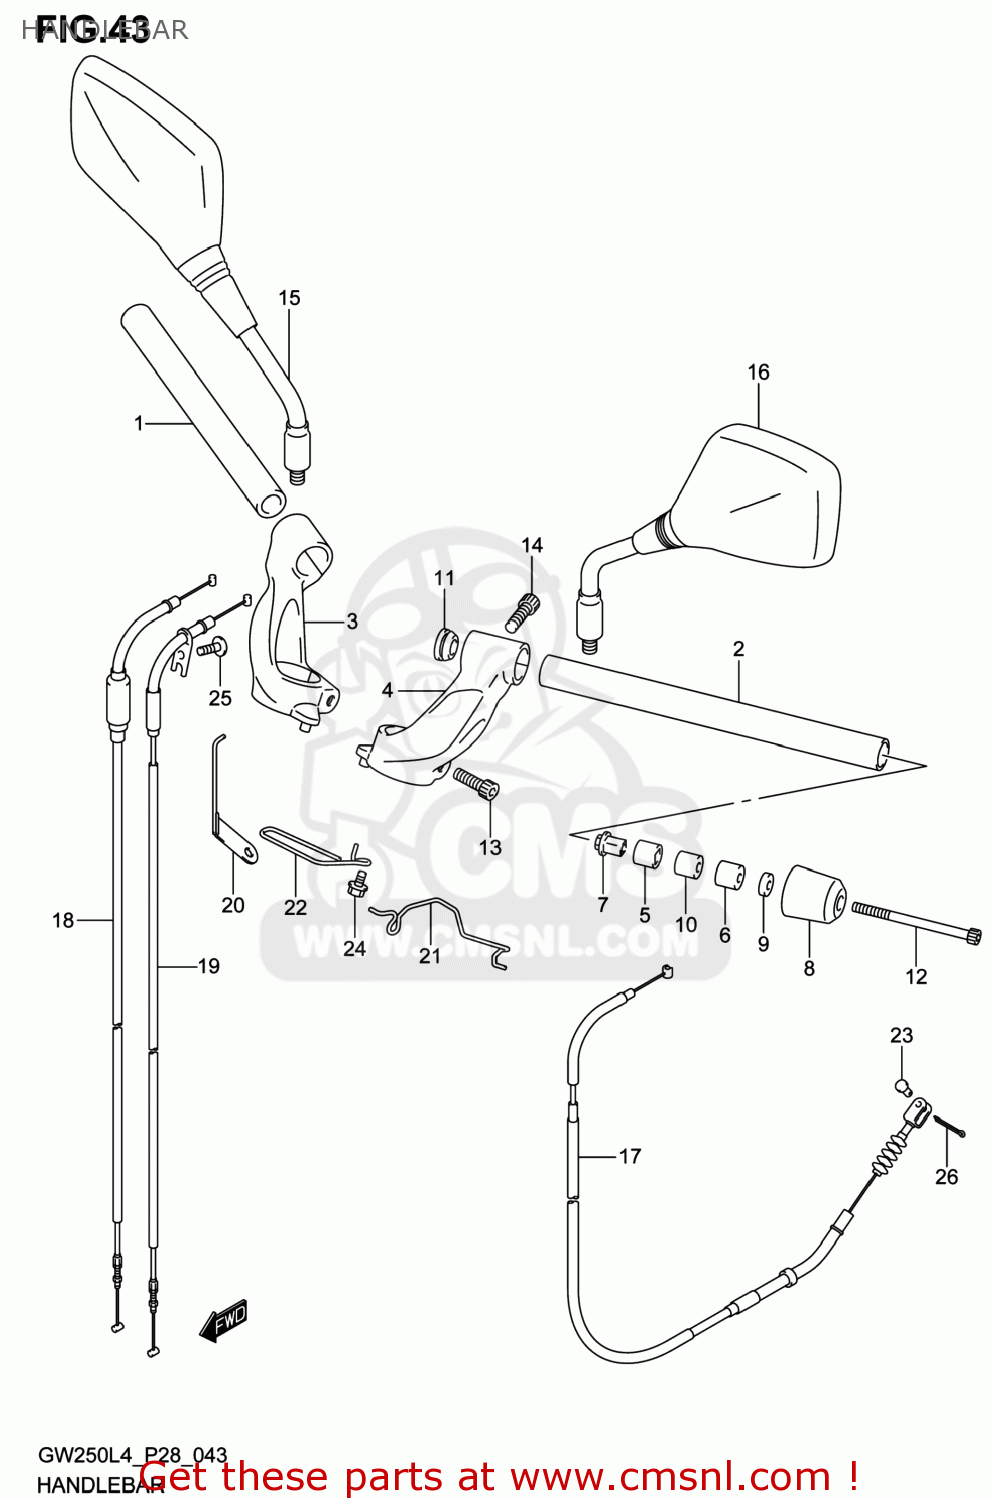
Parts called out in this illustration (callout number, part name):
1	HANDLEBAR,R
2	HANDLEBAR,L
3	HOLDER,HANDLEBAR,R
4	HOLDER,HANDLEBAR,L
5	EXPANDER,HANDLE BALANCER
6	EXPANDER,HANDLE BALANCER
7	NUT,HANDLE BALANCER
8	BALANCER,HANDLEBAR
9	WASHER(6.5X16X4)
10	SPACER(6.5X16X15)
11	PLUG(OD:22)
12	BOLT
13	BOLT
14	BOLT
15	MIRROR ASSY,RR VIEW,R
16	MIRROR ASSY,RR VIEW,L
17	CABLE ASSY,CLUTCH
18	CABLE ASSY,THROTTLE NO.1
19	CABLE ASSY,THROTTLE NO.2
20	GUIDE,CABLE
21	GUIDE,CLUTCH CABLE
22	GUIDE,CABLE
23	PIN
24	BOLT
25	SCREW
26	PIN
